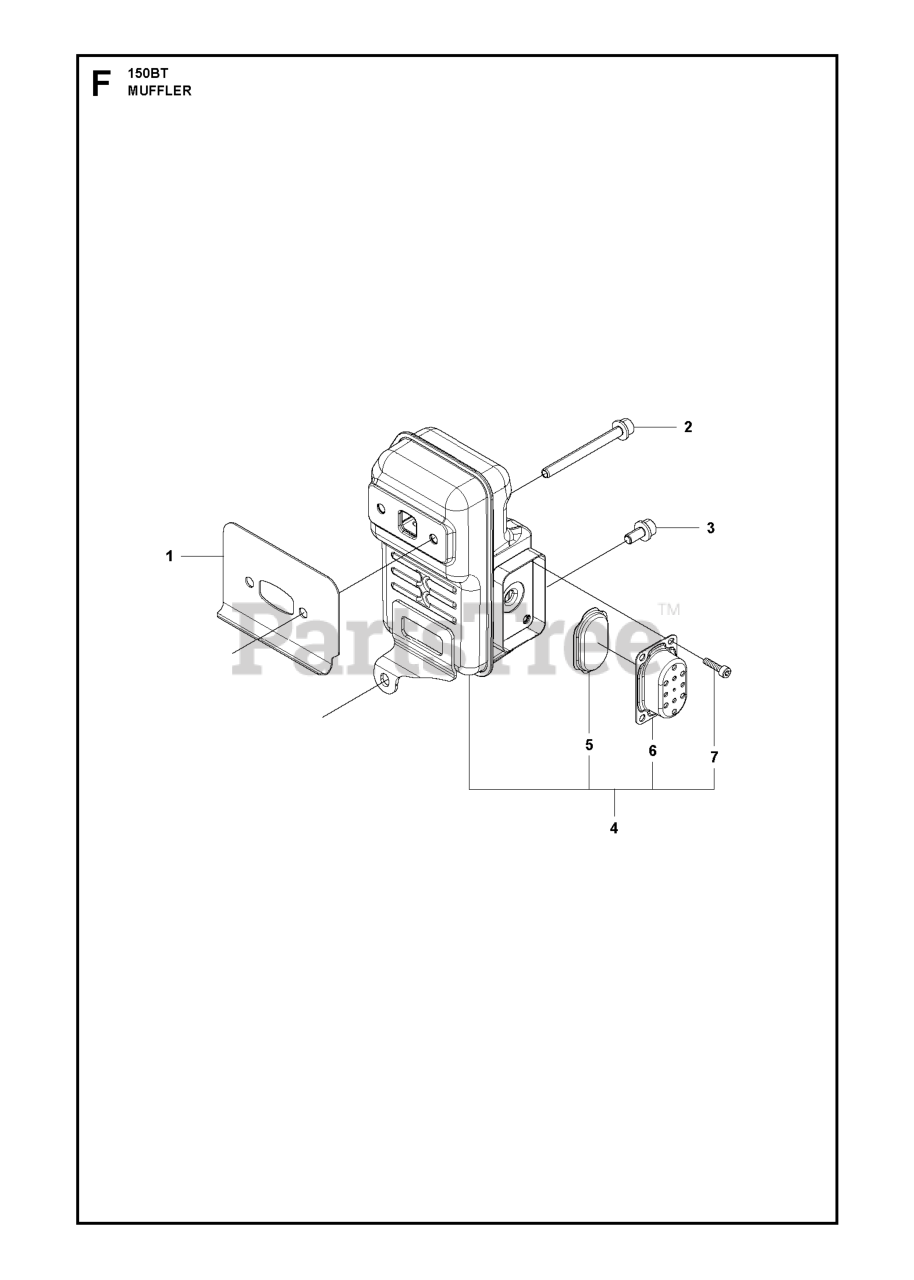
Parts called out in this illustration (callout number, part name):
1	GASKET.MUFFLER
1	GASKET
2	BOLT
4	MUFFLER ASSY
5	SPARK ARRESTOR SCREEN
6	EXHAUST DUCT
